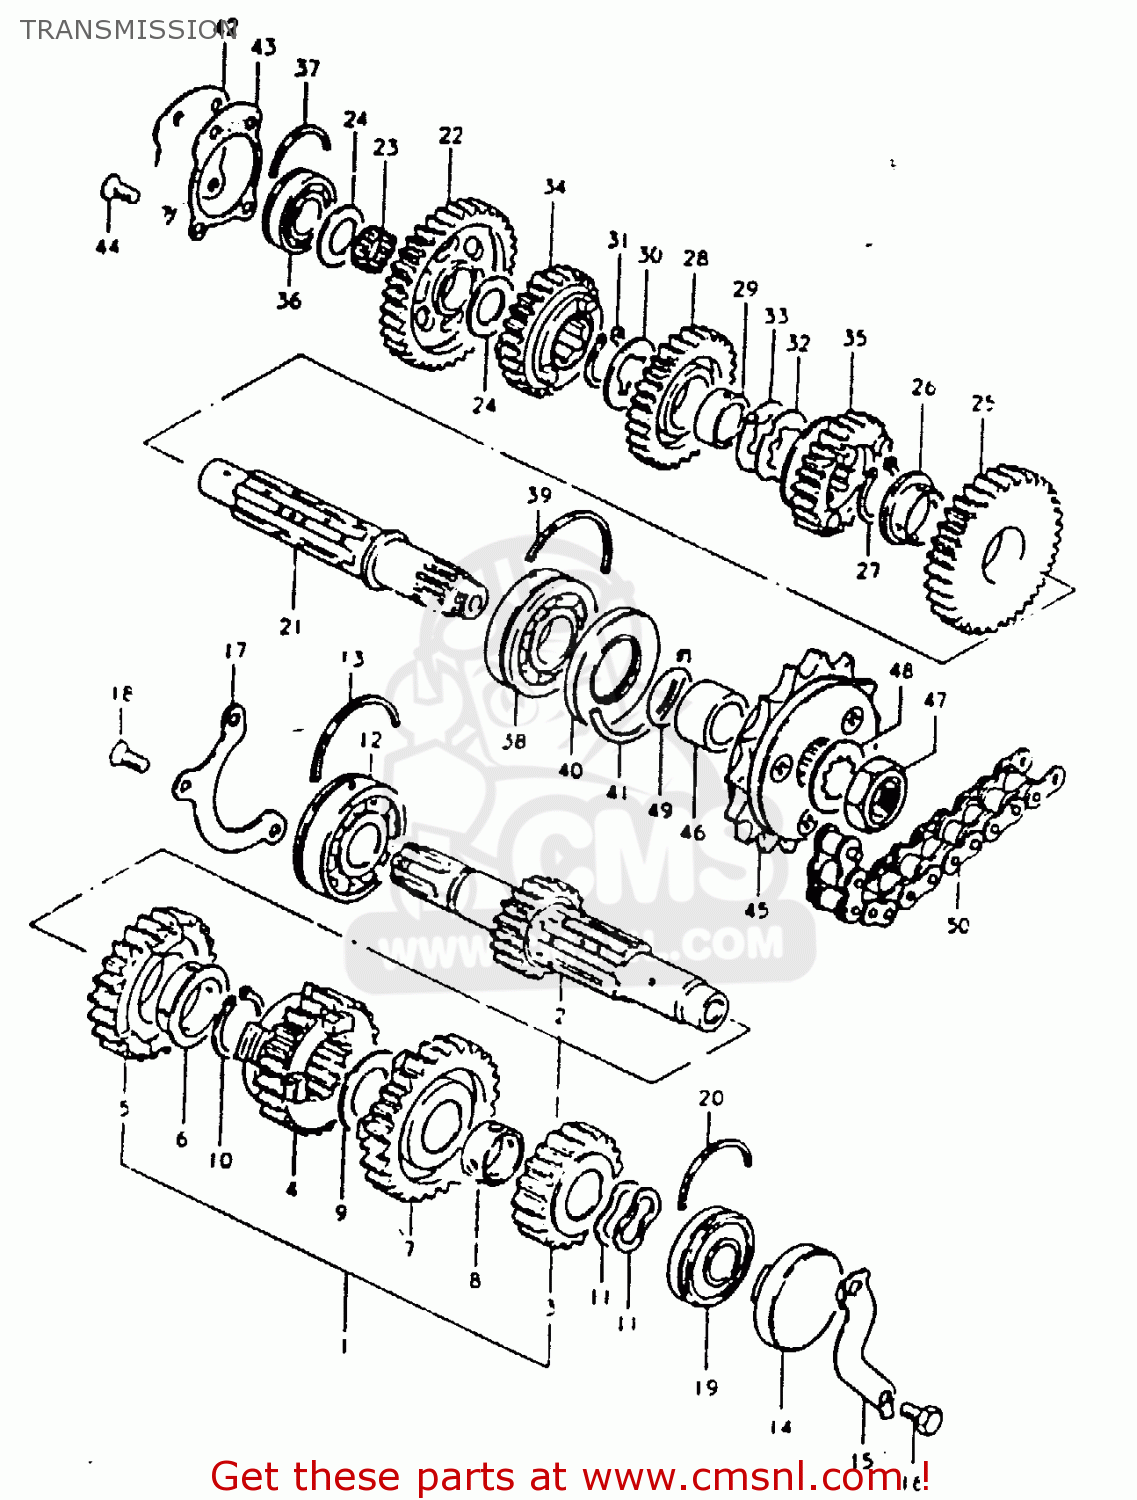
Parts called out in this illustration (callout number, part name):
1	SHAFT,COUNTER
2	SHAFT,COUNTER
3	GEAR,SECOND DRIVE
4	GEAR,3RD DRIVE(NT:21)
5	GEAR,FOURTH DRIVE
6	BUSH(28X32X2)
7	GEAR,FIFTH DRIVE
8	BUSHING
9	WASHER
10	CIRCLIP
11	WASHER
12	BEARING(25X62X17)
13	C-RING
14	PLUG
15	RETAINER,CL PUSH ROD OIL SEAL
16	BOLT
17	RETAINER,CNTR SHAFT BEARING
18	SCREW
19	BEARING(20X47X14)
20	C RING
21	SHAFT,DRIVE
22	GEAR,FIRST DRIVEN (NT:35)
23	BEARING(20X24X10).8
24	WASHER
25	GEAR,SECOND DRIVEN
26	BUSH(28X32X2)
27	CIRCLIP
28	GEAR,THIRD DRIVEN
29	BUSH,3RD DRIVEN GEAR
30	WASHER,LOCK
31	CIRCLIP
32	WASHER,LOCK
33	WASHER
34	GEAR,FOURTH DRIVEN
35	GEAR,FIFTH DRIVEN
36	BEARING
37	C RING
38	BEARING(25X62X17)
39	C-RING
40	SEAL,OIL(32X62X7)
41	C RING
42	PLATE,DRIVE SHAFT
43	GASKET,DRIVESHAFT PLATE (MCA)
44	SCREW
45	SPROCKET,ENGINE
46	SPACER(25X32X18.6)
47	NUT
48	WASHER
49	O RING(D:1,ID:24.5)
50	CHAIN ASSEMBLY,DRIVE
